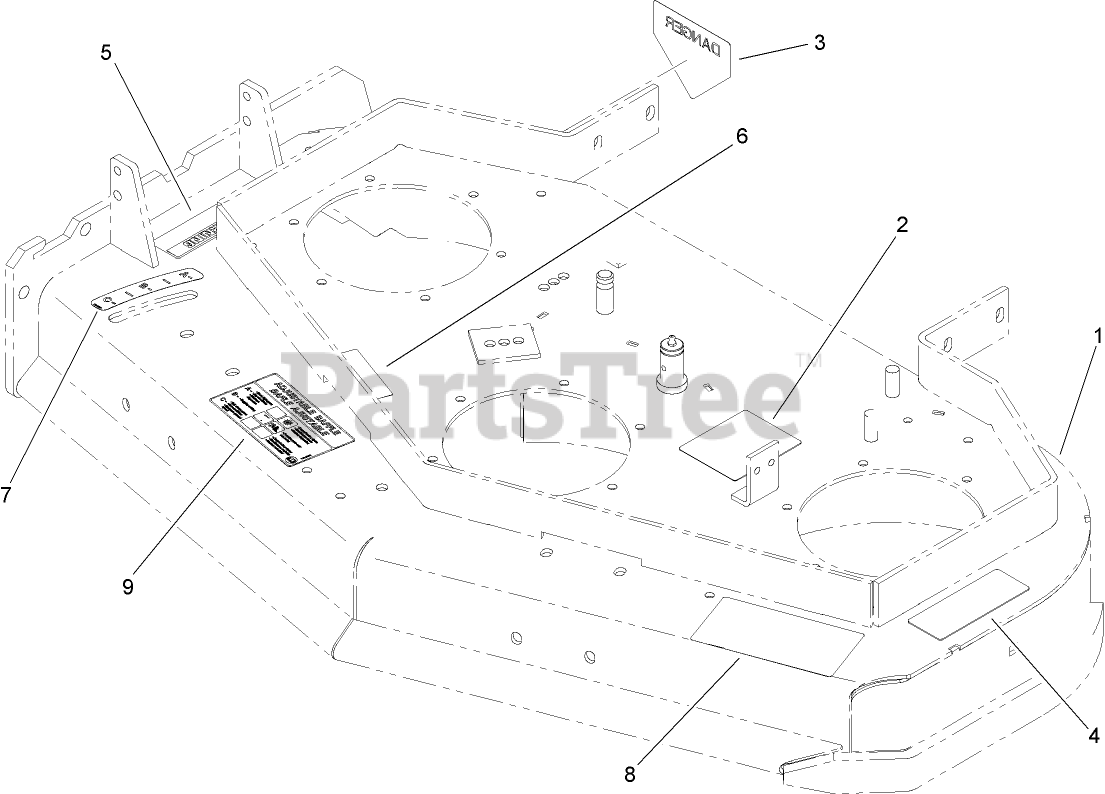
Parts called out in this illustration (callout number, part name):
1	40 INCH DECK ASM
2	DECAL-ROUTING, BELT
3	DECAL-DANGER
4	DECAL-TORQUE, BOLT
5	DECAL-WARNING
6	DECAL-COVER, MISSING
7	DECAL-SETTING, BAFFLE
8	DECAL-DANGER, THROWN OBJECT
9	DECAL-ADJUSTMENT, BAFFLE
